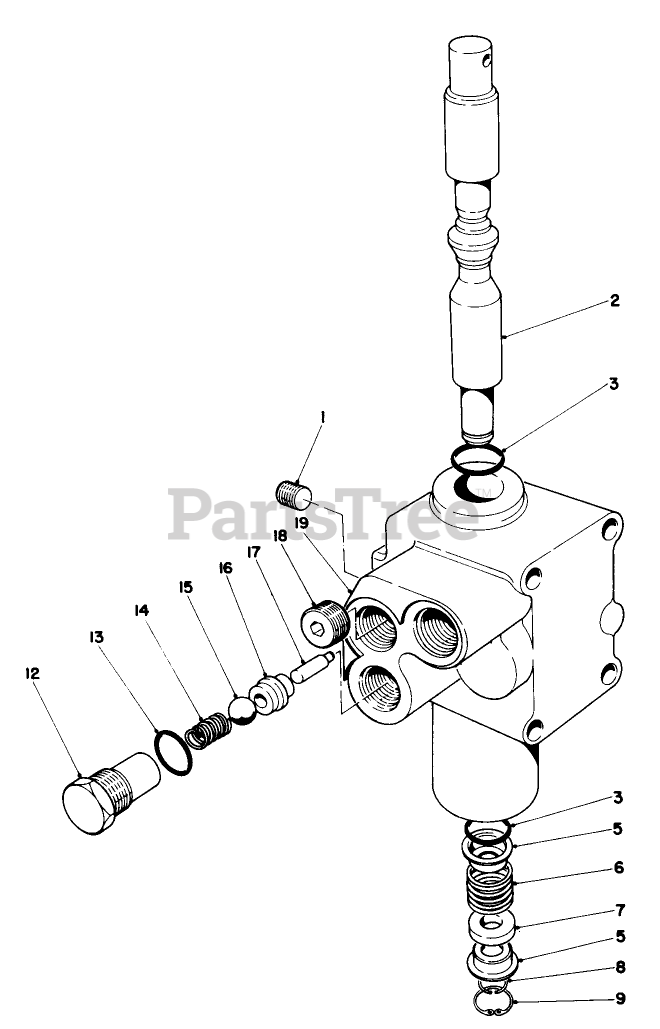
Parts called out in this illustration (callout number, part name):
2	SPOOL
3	O-RING
5	RETAINER
6	SPRING
7	FLOAT SPACER
8	RING-SNAP
9	RING-SNAP
13	0-Ring
14	SPRING
16	SEAT-VALVE
19	Bode
